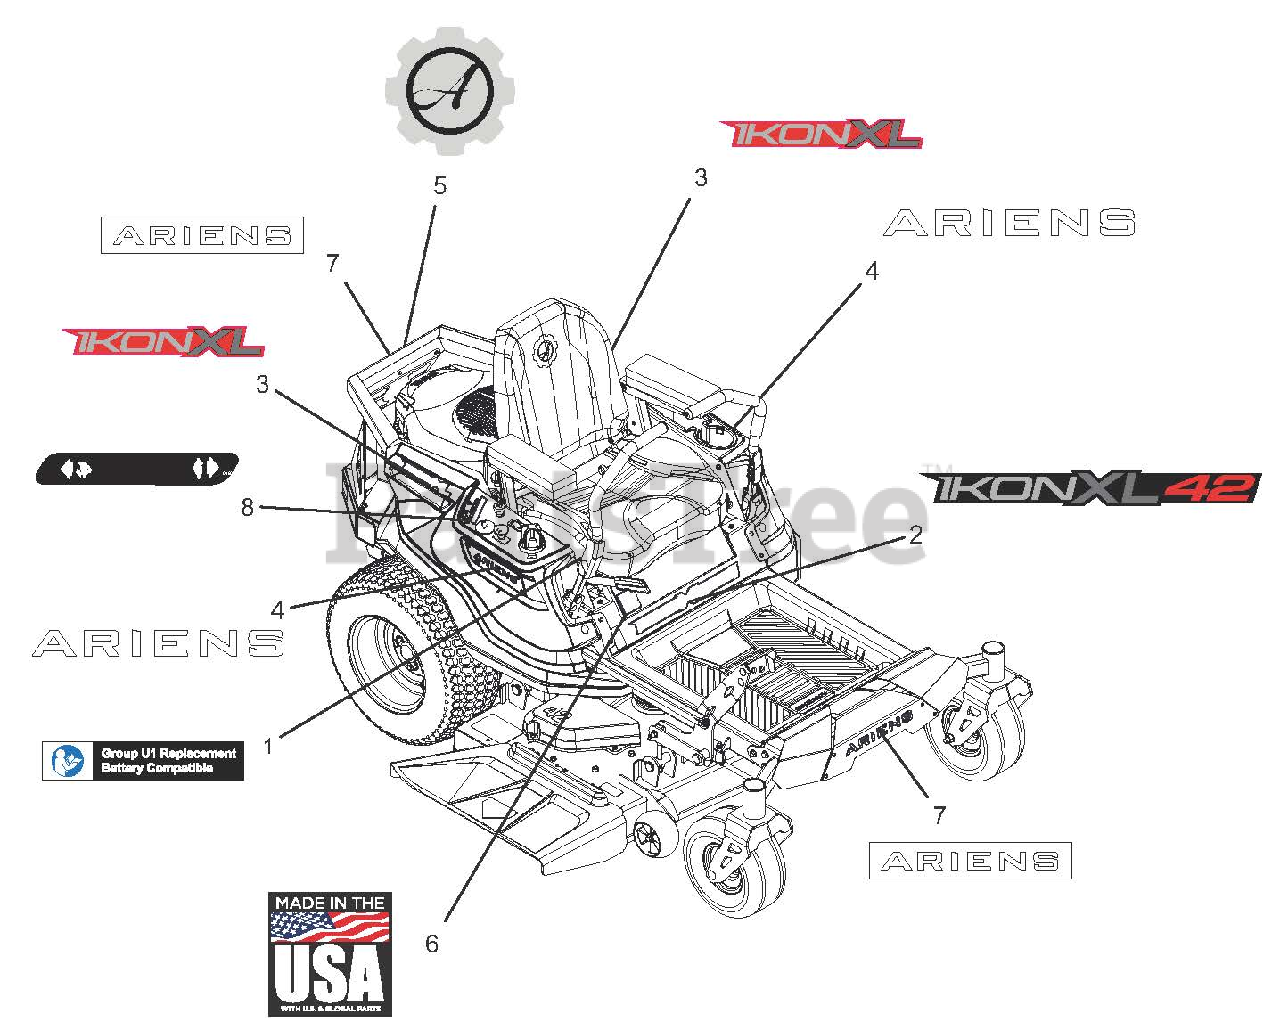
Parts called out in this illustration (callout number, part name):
1	DECAL, U1 BATTERY REPLACEMENT
2	DECAL, IKON-XL 42"
3	DECAL, IKON-XL
4	DECAL, ARIENS (6.50")
5	DECAL, ARIENS-GEAR BADGE
6	DECAL, MADE IN USA
7	DECAL - ARIENS 9.625"
8	DECAL, DASH DECAL
